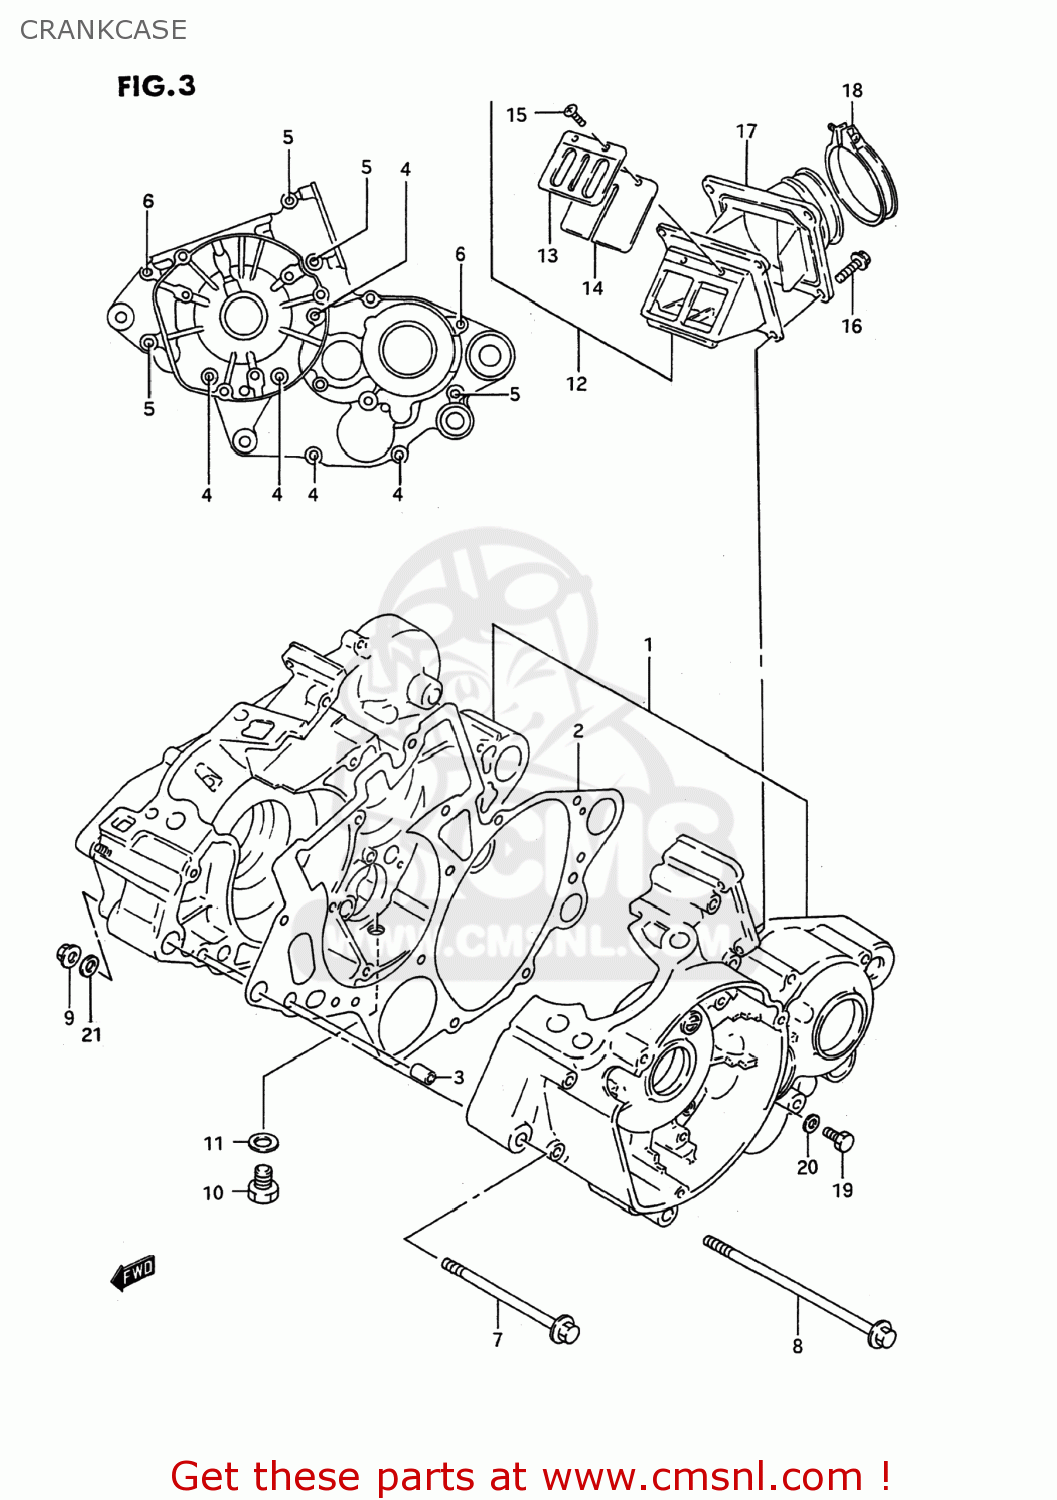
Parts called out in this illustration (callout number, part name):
1	CRANKCASE SET
2	GASKET,CRANKCASE (NAS)
3	PIN
4	BOLT
5	BOLT
6	BOLT
7	BOLT(8X88)
8	BOLT(8X125)
9	NUT
10	Bolt
11	GASKET(12.1X16.2X3.7) (NAS)
12	VALVE ASSEMBLY,REED
13	STOPPER,REED VALVE
14	VALVE,REED
15	SCREW
16	BOLT
17	PIPE,INTAKE
18	CLAMP
19	SCREW(6X10)
20	GASKET(6.2X11X1).2 (NAS)
21	WASHER
